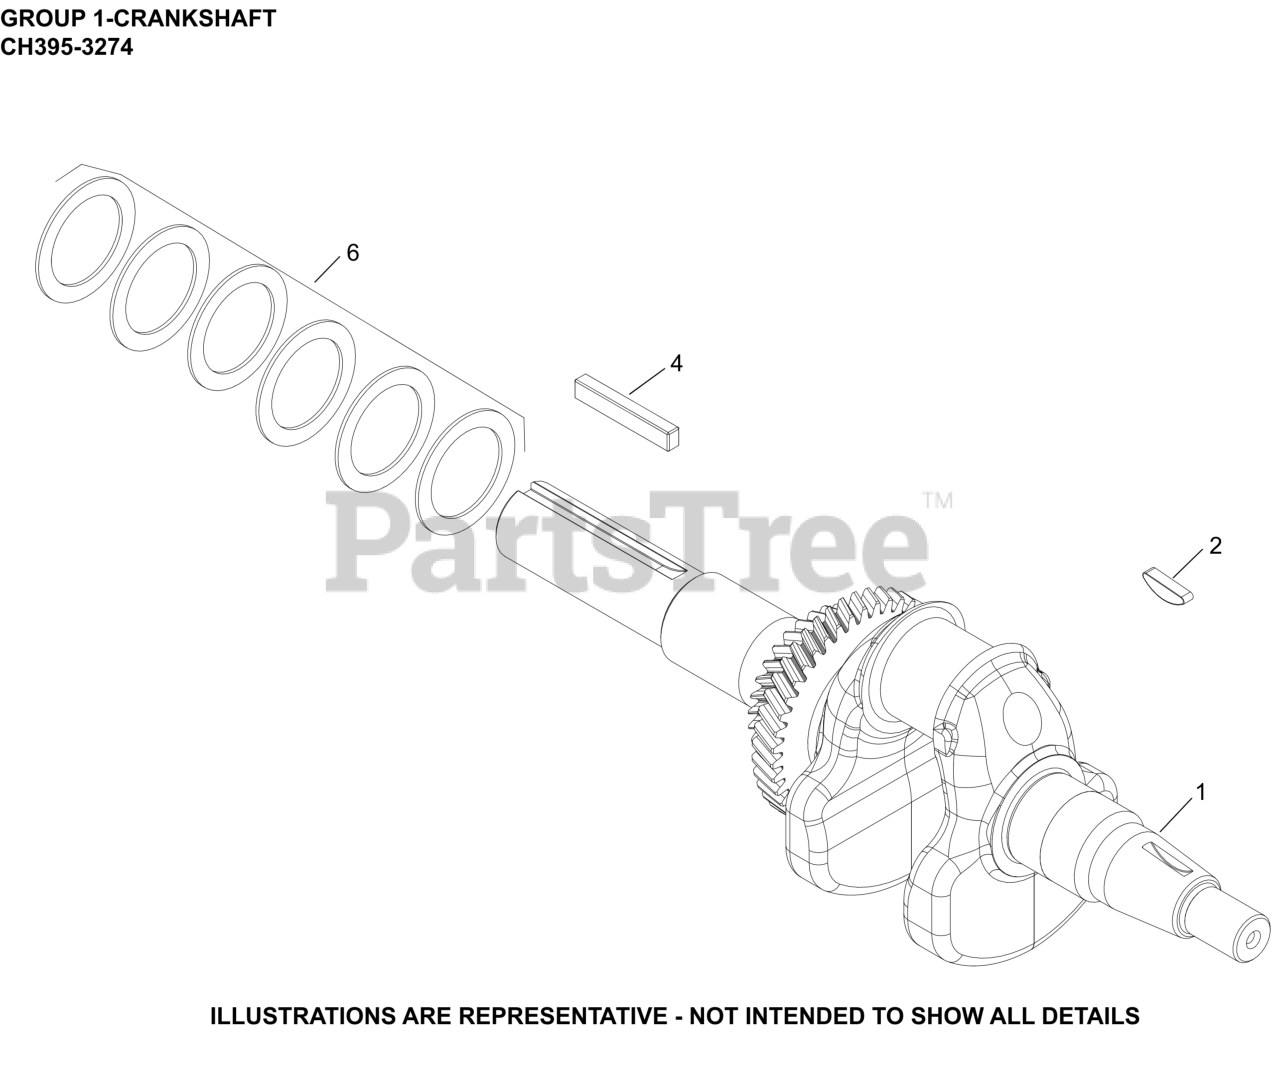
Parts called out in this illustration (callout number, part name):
1	CRANKSHAFT ASSEMBLY
2	KEY, FLYWHEEL
4	KEY, SQUARE
6	KIT, SHIMS
